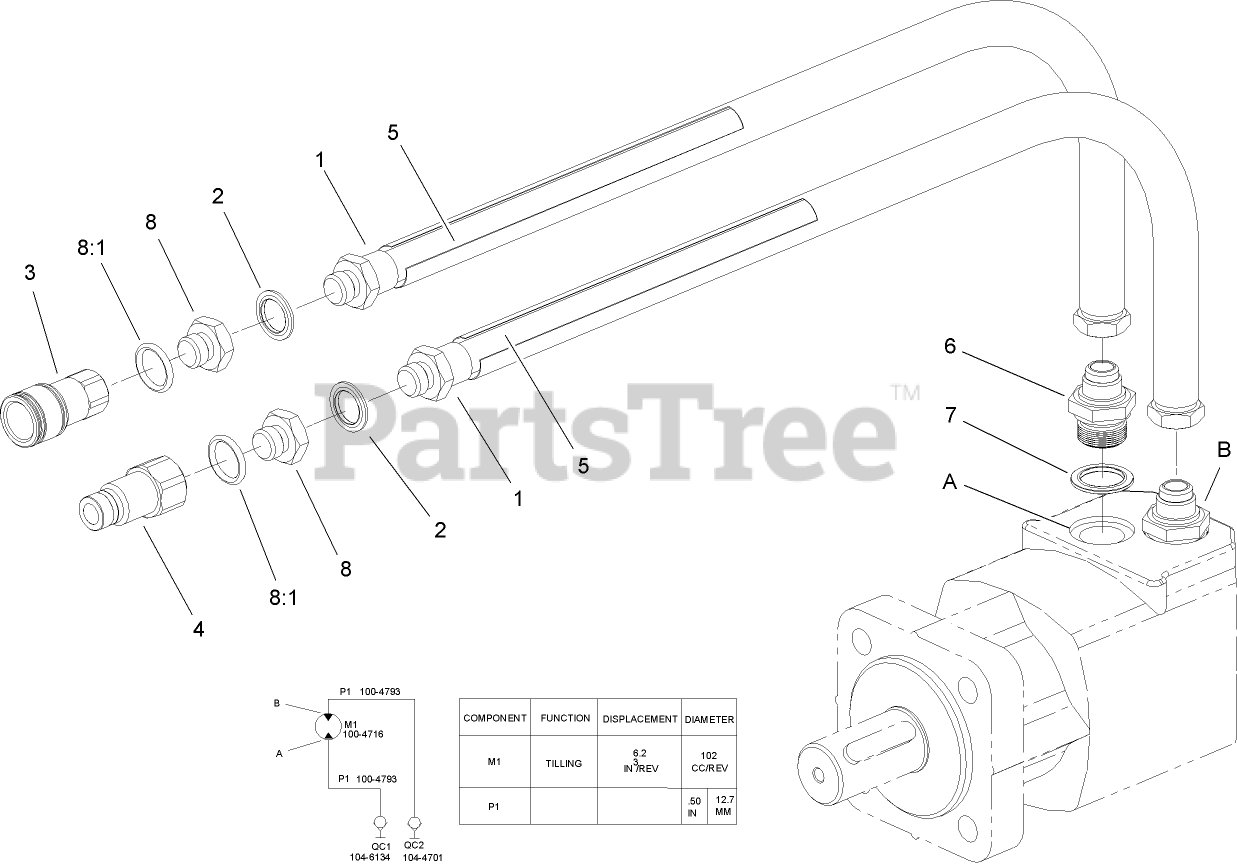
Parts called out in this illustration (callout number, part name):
1	HYDRAULIC HOSE ASM
2	GASKET
3	COUPLER-FACE, FLUSH
4	NIPPLE-CONNECT, PRESSURE
5	SHEATH-PROTECTION, HOSE
6	ADAPTER-HYD
7	GASKET
8	ADAPTER-HYD
8:1	O-RING
